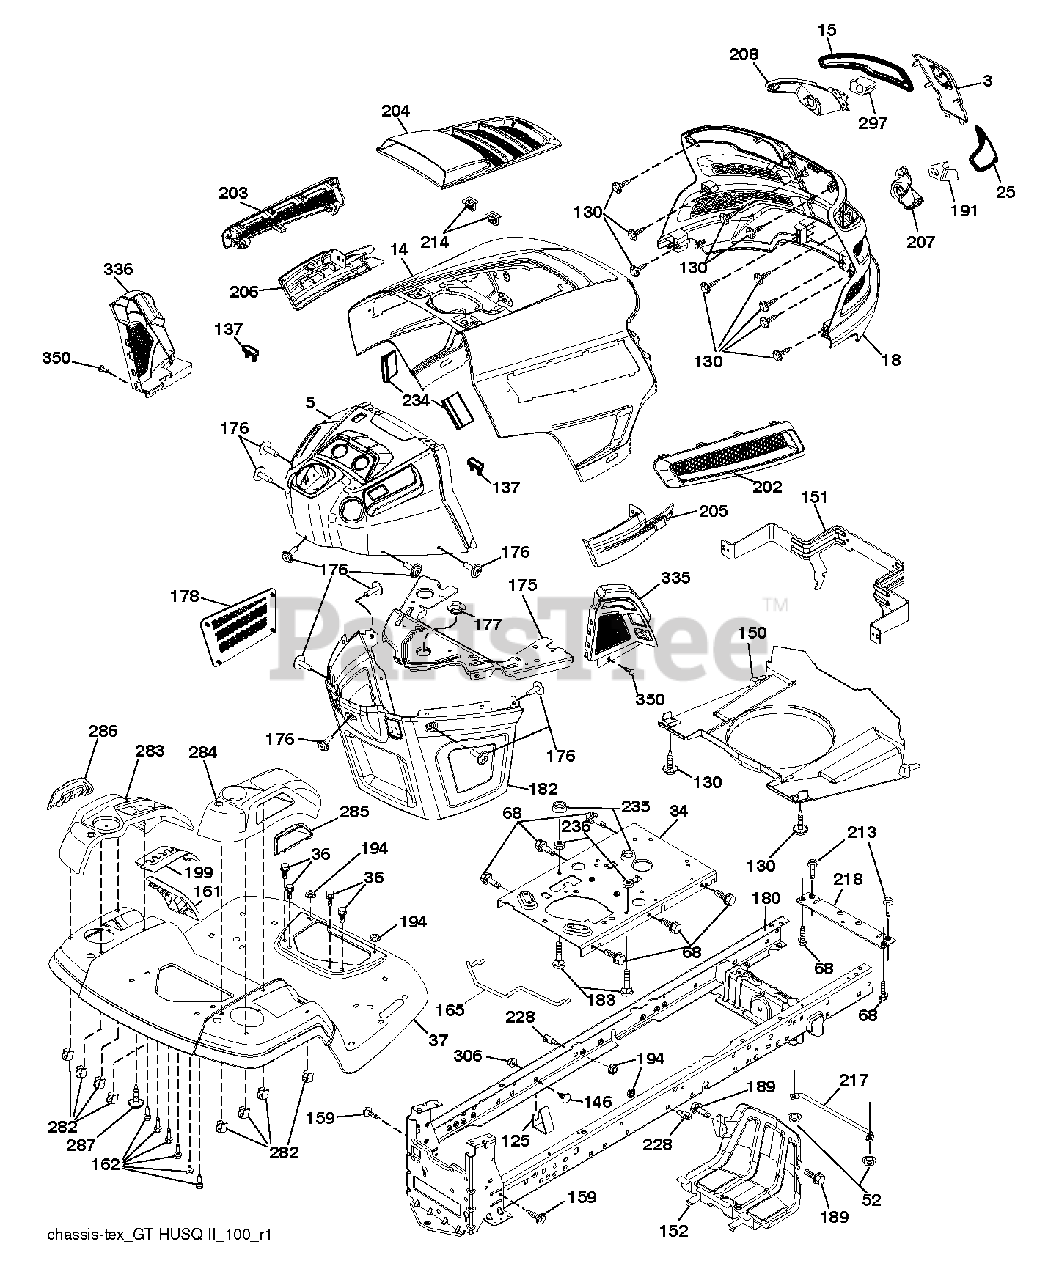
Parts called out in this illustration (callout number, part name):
3	APPLIQUE.SUBASM.GT.HUSQ.II
5	DASH.UPP.GT2.DUAL.RD.PTO.MCHOK
14	HOOD.ASM.HUSQVARNA.GT.TEX.ORAN
15	LENS.HEADLIGHT.LH.GTII.2011
18	GRILLE.SUBSTRATE.2011.
25	LENS.HEADLIGHT.RH.GTII.2011
34	PLATE.ENGINE.WELDED.CHASSIS
36	SCREW 5/16"
37	FENDER.TLT.FS.W/CPH/FW/RSF.668
52	LOCKNUT
68	SCREW LT
125	CLIP.FUEL.LINE
130	SCREW.#10 X 0.750.BOS
137	BUMPER DASH
146	BOLT.RDHD.SHT.SQNK.3/8-16X5/8
150	AIR.DUCT.GTV.BLACK
151	BRACKET.PIVOT.HOOD.GT.HUSQ.II
152	SHIELD.BROWNING.PNT.GT.V2
159	SCREW, 3/8-16X3/4
161	WINDOW.FUEL.LT.HUSQ.TEX.498
162	SCREW.HI-LO.CONSOLE
165	SUPPORT.TANK.REAR.W/TEX
175	PLATE.CROSSMEMBER.HUSQ
176	SCREW.#10-24X5/8.RN.QU
177	BUSHING, STEERING
178	CARGO.ASM.NET.TXGT.W/C
180	CHASSIS
182	DASH.LOWER.COMMON.12V.ADAPTOR
183	BOLT.5/16-18X1-1/4 FULL THD
189	SCREW
191	INSERT.REFLECTIVE.RH.HUSQ.GTII
194	NUT LOCK HEX FLANGE 5/16-18
199	PLATE.DECK.LIFT.HUSQ.LT
202	VENT.SIDE.RH.GT.HUSQ.II.
203	VENT.SIDE.LH.GT.HUSQ.II.498
204	VENT.TOP.HUSQ.GT2
205	SIDE.TRIM.RH.GT.HUSQ.II
206	SIDE.TRIM.LH.GT.HUSQ.II.GRAY
207	BEZEL LIGHT.RH.GT.II.MYLAR
208	BEZEL LIGHT.LH.GT.II.MYLAR
213	BOLT
214	CLIP.RETAINER.TINNER.
217	ROD.PIVOT.HOOD
218	X-PIECE.HOOD.STOP.NON/
228	STUD.FASTNER.W/ANTI-ROTATE
234	BUMPER.HOOD.TEX.HUSQVARNA
235	SPACER FENDER
236	NUT.CENTERLOCK.5/16-
282	CLIP.RETAINER.CONSOLE.LT.HUSQ
283	CONSOLE.DECK.LIFT.R.SDFL.HUSQ
284	CONCOLE.CNTRL.PDL.HUSQ.LT.498
285	CONSOLE INSERT RH
286	CONSOLE.INSRT.LH.HUSQ.LT.BLACK
287	SCREW 1/4X20
297	INSERT.REFLECTIVE.LH.HUSQ.GTII
306	NUT LOCK FLG 3/8-16 UNC
335	COVER.LOWER.DASH.RH.BLACK
336	COVER-LH.LOWER.DASH.GT2.BLACK
350	CLIP.X-MAS.TREE
